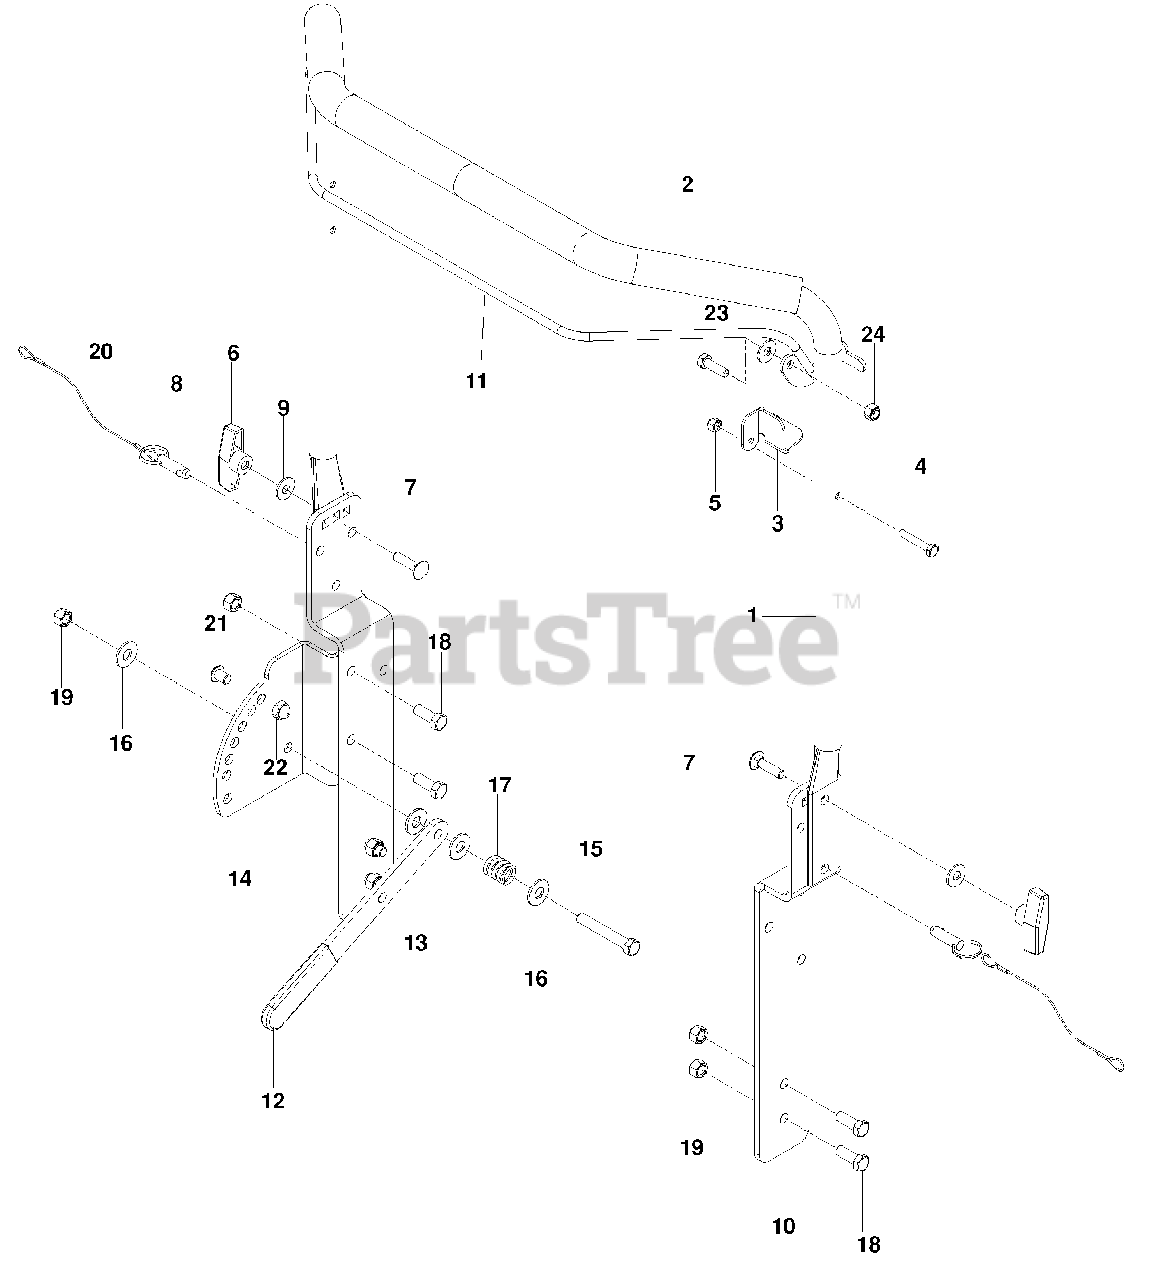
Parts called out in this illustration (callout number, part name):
4	HCS 1/4-20 x 1 1/2
5	NUT 1/4-20 NYLOC
7	RHSNB 5/16-18 x 1 1/4
9	WASHER 5/16 FLAT
10	HANDLE SIDE
12	GRIP, LEVER
14	PLATE, HEIGHT
15	HCS 3/8-16 x 2
16	WASHER 3/8 FLAT
18	HCS 3/8-16 x 1
19	NUT 3/8-16 NYLOC
21	SCREW 3/8-16 BUTTON HD
22	NUT 3/8-16 ACORN
23	HCS 5/16-18 x 1
24	NUT 5/16-18 NYLOC
